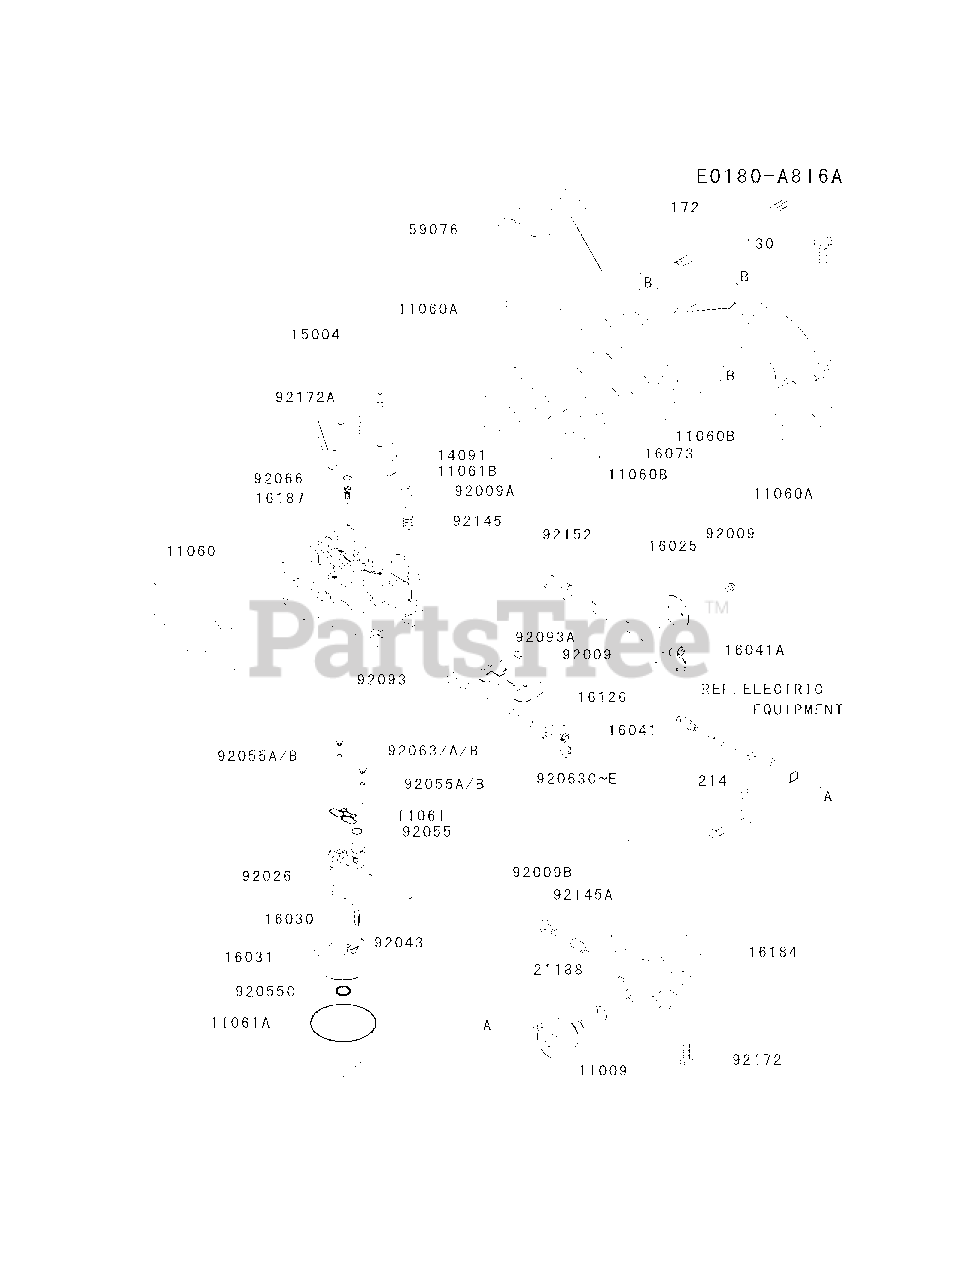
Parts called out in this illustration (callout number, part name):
130	BOLT-FLANGED,6X20
172	BOLT-STUD,6X105
214	SCREW-PAN+-,5X10
